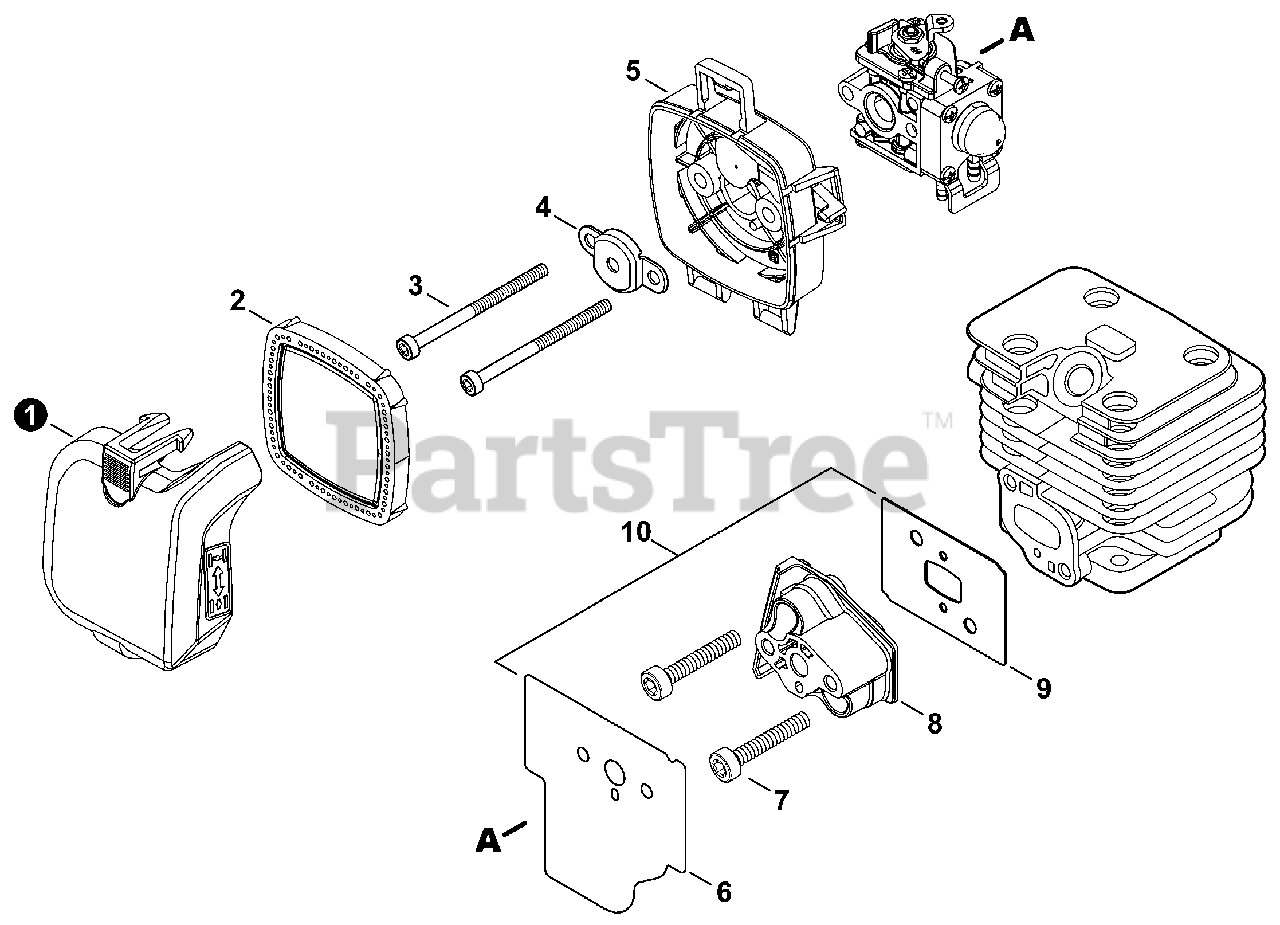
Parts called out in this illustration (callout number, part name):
1	COVER, AIR FILTER
2	FILTER, AIR
3	BOLT, TORX 5×65
4	PLATE, PREVENT
5	CASE ASSY, AIR FILTER
6	GASKET, INTAKE
7	BOLT, TORX 5×20
8	INSULATOR, INTAKE
9	GASKET, INTAKE
10	GASKET KIT
